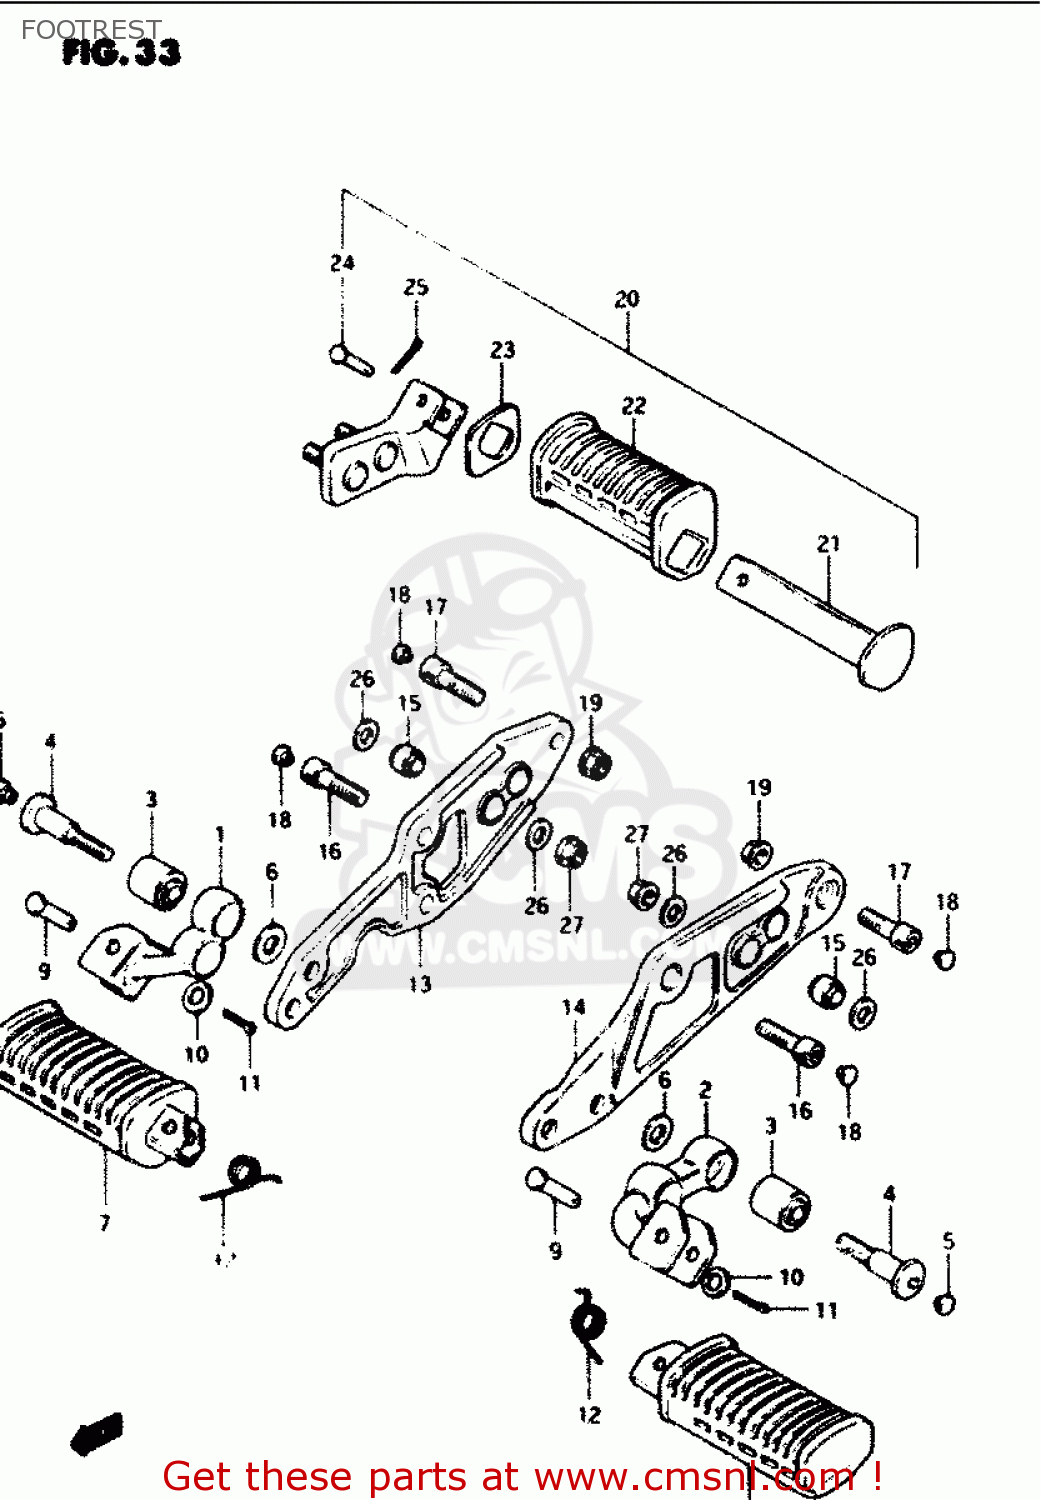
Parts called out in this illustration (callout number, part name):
1	BAR,FRONT FOOTREST,RIGHT
2	BAR,FRONT FOOTREST,LEFT
3	BUSH
4	BOLT(10X50)
5	CAP
6	WASHER (10X18X3.2)
7	RUBBER,FRONT FOOTREST
8	FOOTREST
9	PIN
10	WASHER
11	PIN 20X20
12	SPRING
13	BRACKET,MUFFLER,RIGHT
14	BRACKET,MUFFLER,LEFT
15	BUSH
16	BOLT
17	BOLT, REAR
18	CAP
19	NUT
20	FOOTREST ASSEMBLY,REAR
21	BAR,REAR FOOTREST
22	RUBBER,RR FOOTREST
23	WASHER,RR FOOTREST RUBBER
24	PIN
25	PIN 20X20
26	WASHER(10.5X20X3.2)
27	NUT
